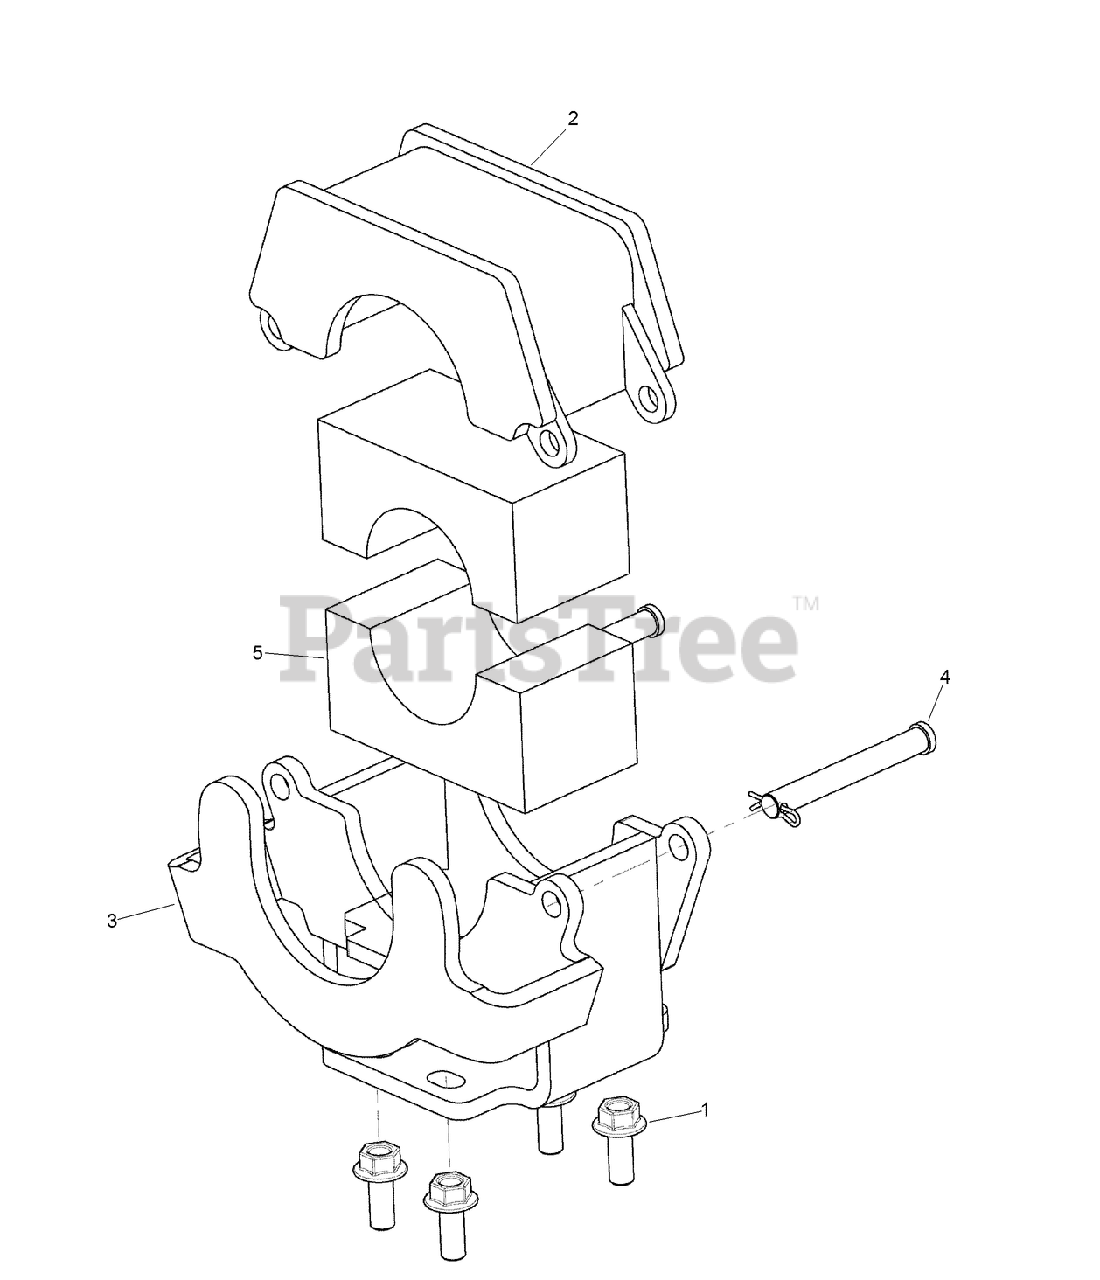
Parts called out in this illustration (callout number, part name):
1	SCREW, METRIC FLANGE w/BODY-M12 x 30
2	WELDMENT - Rod Guide
3	WELDMENT - Rod Guide
4	PIN - Clevis, with Cotter Pin Retainer
5	BUSHING-GUIDE, ROD
